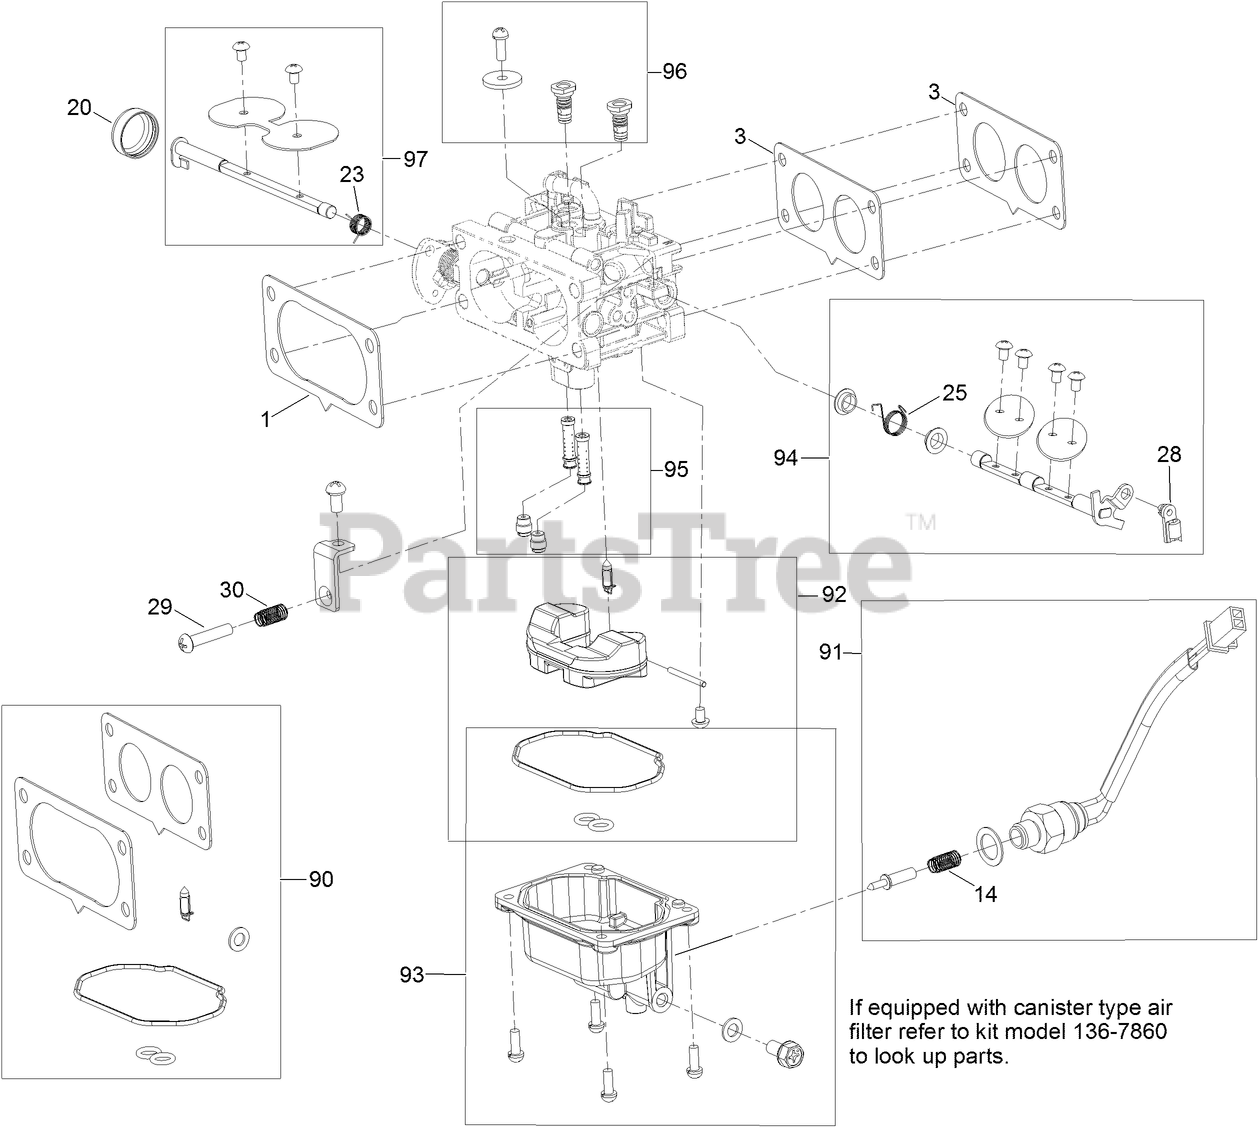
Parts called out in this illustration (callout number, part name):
1	GASKET-CARBURETOR
3	GASKET-CARBURETOR
14	SPRING
20	COVER-SHAFT, CHOKE
23	SPRING
25	SPRING
28	CLAMP-LOCK
29	SCREW-PPH
30	SPRING
90	CARBURETOR REPAIR KIT
91	SOLENOID KIT
92	FLOAT KIT
93	BOWL KIT
94	THROTTLE SHAFT KIT
95	NOZZLE AND JET KIT
96	AIR JET KIT
97	CHOKE SHAFT KIT
